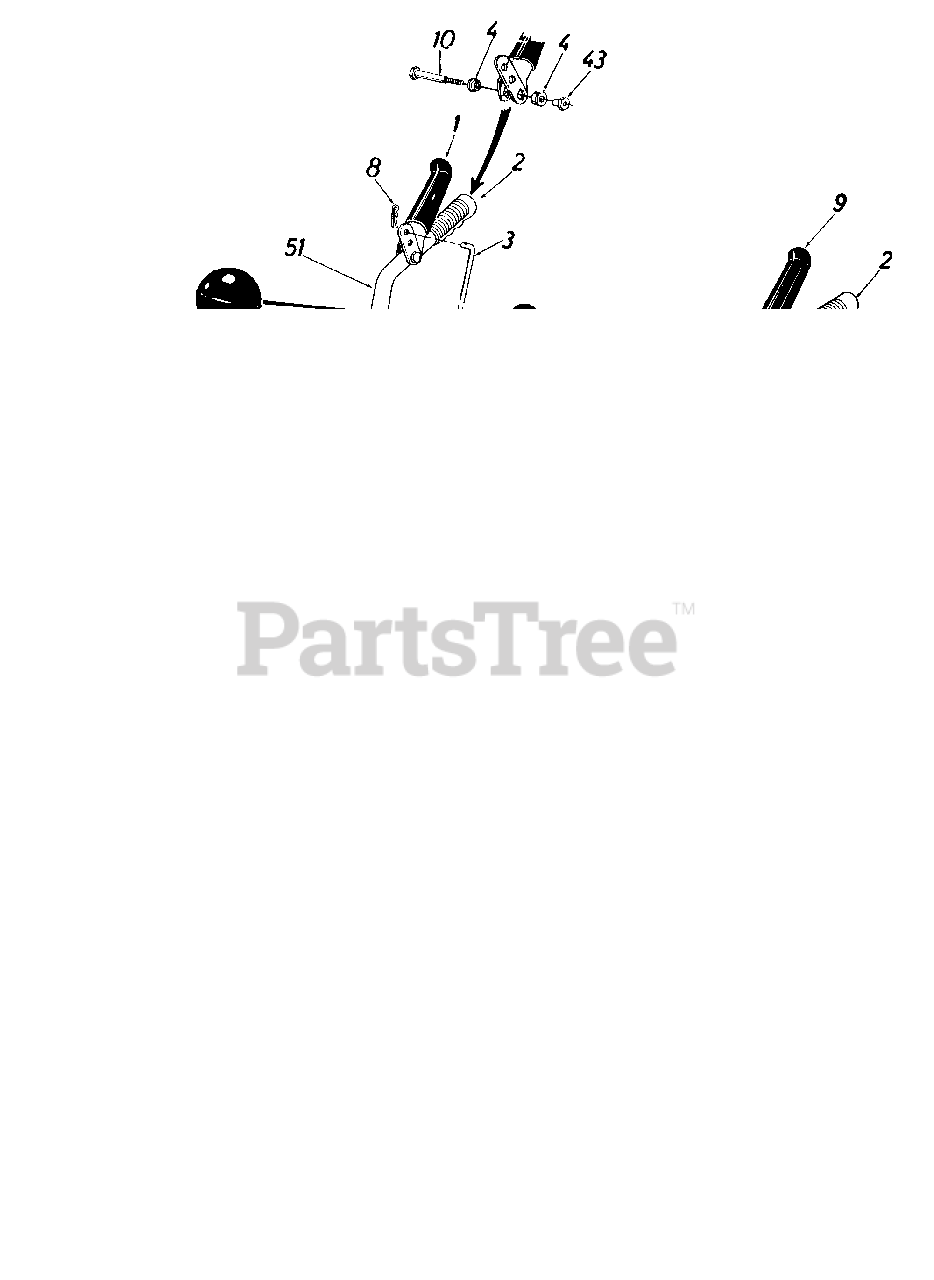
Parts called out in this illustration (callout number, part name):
1	Clutch Grip Ass'y. R.H.
2	Hand Grips
3	Lockout Cable 30.5" Lg.
4	Hex Flange Brg. Plastic .38" I.D.
6	Plastic Plug
7	Carriage Bolt 5/16-18 x 2.0" Lg.
8	Internal Cotter Pin
9	Clutch Grip Ass'y. L.H.
10	Shld Bolt .374" Dia. x 1.53" Lg.
11	Upper Handle Half L.H.
12	Hand Knob
13	Belleville Wash. 5/16" I.D.
14	Push Nut 3/8" Rod
15	Knob 3/8" I.D.
16	Roll Pin .12 Dia. x .63" Lg.
17	Eyebolt
18	Chute Crank Ass'y.
19	Hex Nut 5/16-18 Thd.
21	Plastic Bushing
22	Shifting Rod
23	Lower Handle Half L.H.
24	Extension Spring .75" O.D. x 5.0" Lg.
25	Hex Ins. L-Nut 1/4-20 Thd.
26	Shifting Linkage Bracket
27	Belleville Wash. .40 I.D. x .88 O.D. x .060
28	Hex Bolt 3/8-16 x 2.0" Lg.
29	Hex Wash. Hd. Self-Tap Scr. 3/8-16 x .75" Lg.
30	Frame Cover
31	Hex Wash. Hd. Self-Tap Scr. 1/4-20 x .50" Lg.
32	Extension Spring .38" O.D. x 3.25" Lg.
33	Hex Jam Nut 3/8-16 Thd.
34	L-Wash. 3/8" I.D.
35	Auger Clutch Brkt. Ass'y.
36	Shld. Bolt .625" Dia. x .170" Lg. (3/8-16)
37	Extension Spring .38" O.D. x 3.25" Lg.
38	Drive Pulley Support Brkt. Ass'y.
39	Cotter Pin 3/32" Dia. x .75" Lg.
40	Drlve Clutch Brkt.
41	Drive Clutch Rod
42	Lower Handle Half R.H.
43	Shld. Nut 1/4-20 Thd.
45	Shift Handle Ass'y.
46	Hex Ins. Jam L-Nut 3/8-24 Thd.
47	Compression Spring .38" O.D. x .88" Lg.
48	Bell-Wash. .40 I.D. x .88 O.D. x .060
49	Cotter Pin 3/32" Dia. x .75" Lg.
50	Handle Panel Ass'y.
51	Upper Handle Half R.H.
52	Bell-Wash. .38 I.D. x 1.12" O.D. x .02
54	Hex Bolt 5/16-18 x 2" Lg.
55	Lockout Cable 36" Lg.
56	Adjustment Ferrule
57	Fl-Wash. .33" I.D. x .63" O.D.
